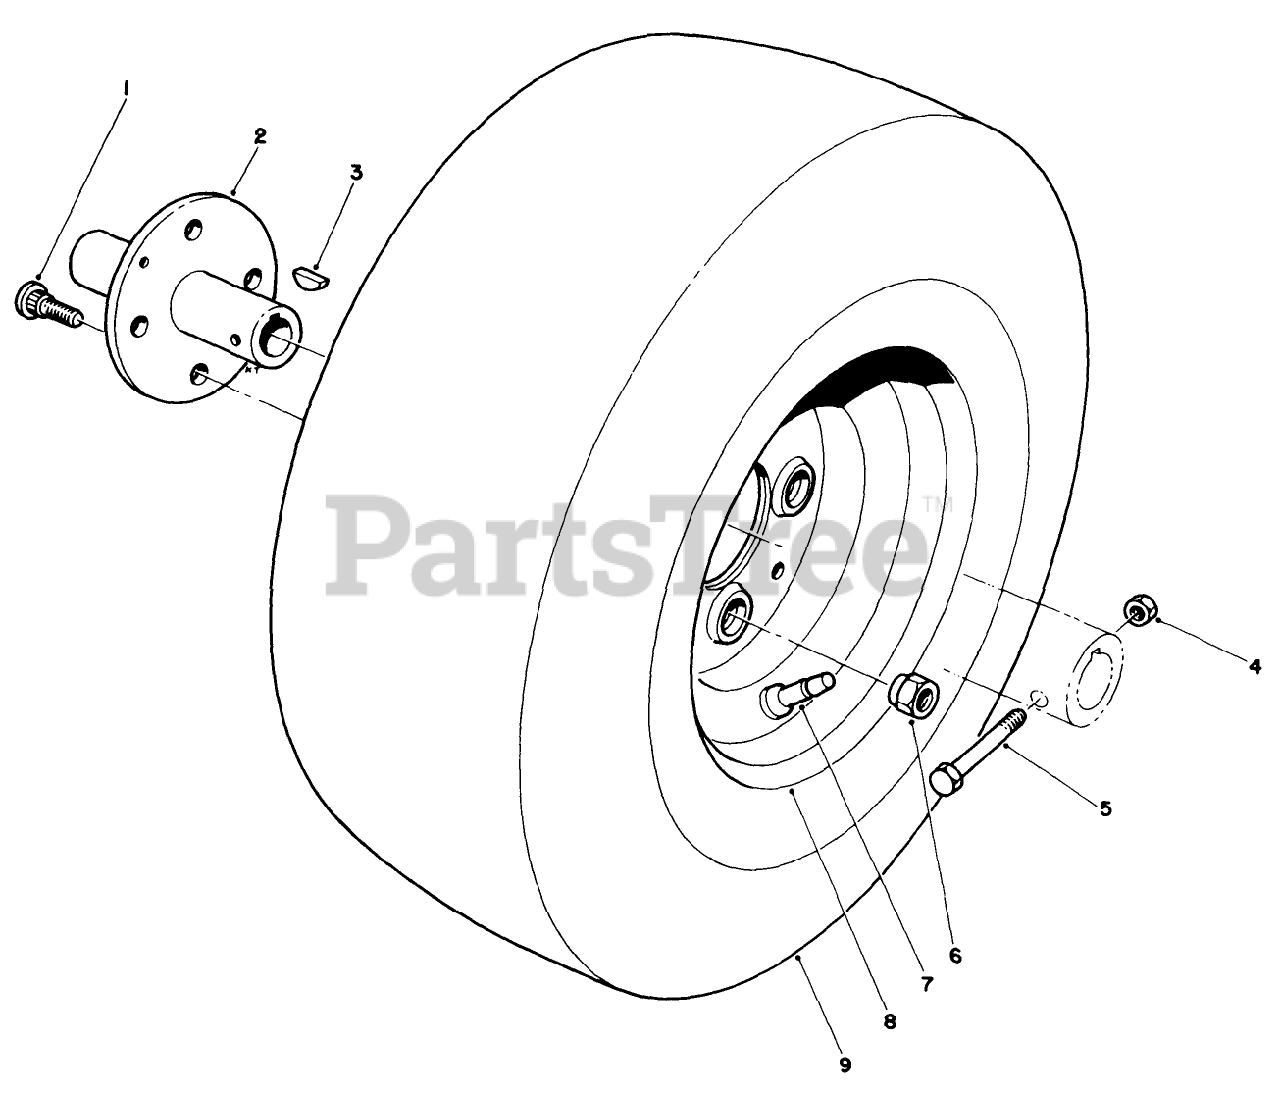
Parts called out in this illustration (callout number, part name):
1	1/2-20X1.25 BOLT
2	WHEEL HUB
3	KEY-WOODRUFF
4	NUT-LOCK, NI
5	SCREW-HH
6	NUT-LUG
7	STEM-VALVE
9	TIRE-4-Ply
